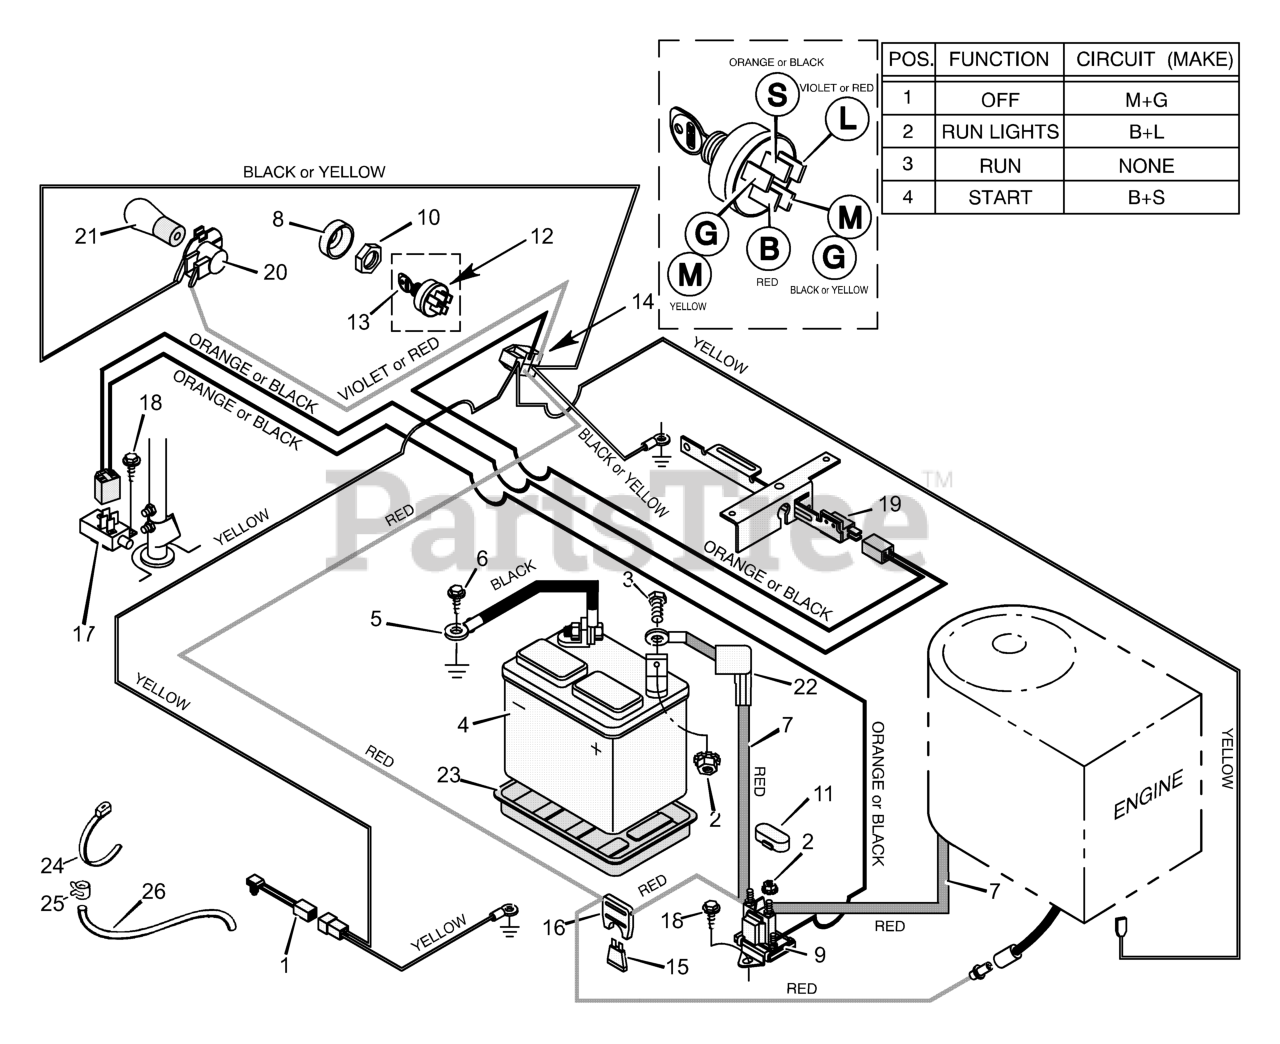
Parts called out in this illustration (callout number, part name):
1	Switch, Seat Sensor
2	Locknut
4	Battery
5	Cable, Battery Ground
7	Cable, Red Battery
8	Cap, Ignition
9	Solenoid
10	Nut, Hex
12	Switch, Ignition
13	Key, Ignition
14	Harness, Chassis wire
16	Holder, Fuse
17	Switch, Limit
19	Switch, Limit
20	Socket, Light
21	Bulb, Light
22	Cover, Terminal
23	Tray, Battery
26	Tube, Drain
